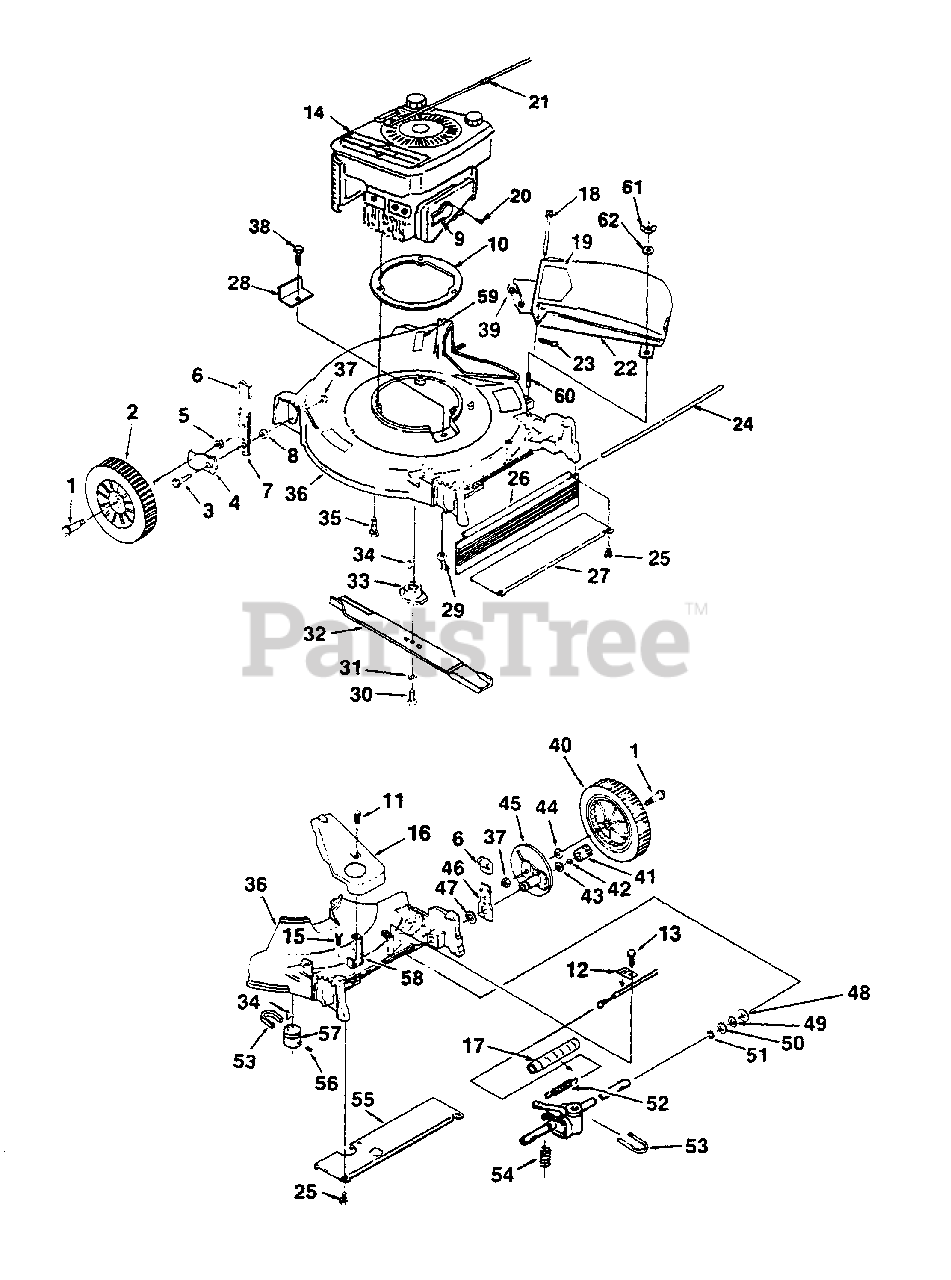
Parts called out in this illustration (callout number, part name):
1	BOLT- Axle
2	WHEEL & TIRE
3	BOLT- Hex hd. 5/16-18
4	ARM- Wheel adjusting
5	NUT
6	KNOB
7	INDEX SPRING & PIN ASSY.
9	DEFLECTOR
10	RING- Engine
11	SCREW- 1/4-20 x 3/4"
12	CLAMP- Cable
13	SCREW- Thd. 1/4-20 x 5/8"
14	ENGINE- 3.5 H.P.
16	COVER- Drive
17	COVER- Spring
18	PIN- Hinge
19	LABEL- Warning
20	SCREW- Sems #8-32 x 3/8"
21	STOP- Rope
22	CHUTE
23	PIN- Cotter 3/32 x 3/4"
25	SCREW- Hex washer hd. 1/4-20 x 3/4"
26	FLAP- Drag
27	COVER- Rear
28	COVER- Belt opening
30	SCREW- Hex hd. 3/8-24 x 1"
31	WASHER- Lock 3/8
32	BLADE
35	SCREW- Hex hd. 3/8-16 x 1 1/2"
37	NUT- Flange 5/16-18
40	WHEEL & TIRE ASSY.
41	PINION- R.H.
45	DR. WHEEL SUPPORT ASSY.
46	INDEX SPRING & PIN ASSY.
50	WASHER- (Shim)
51	RING- Eaton
52	SPRING- Extension
53	BELT- Drive
54	SPRING- Compression
55	COVER- Rear
56	SCREW- Set 1/4-20 x 3/8
57	PULLEY- Drive
58	BRACKET- Gear box cover
59	DECAL- Gasohol
61	WING NUT (HSD20 & HSD20P)
62	WASHER- Flat 1/4"
